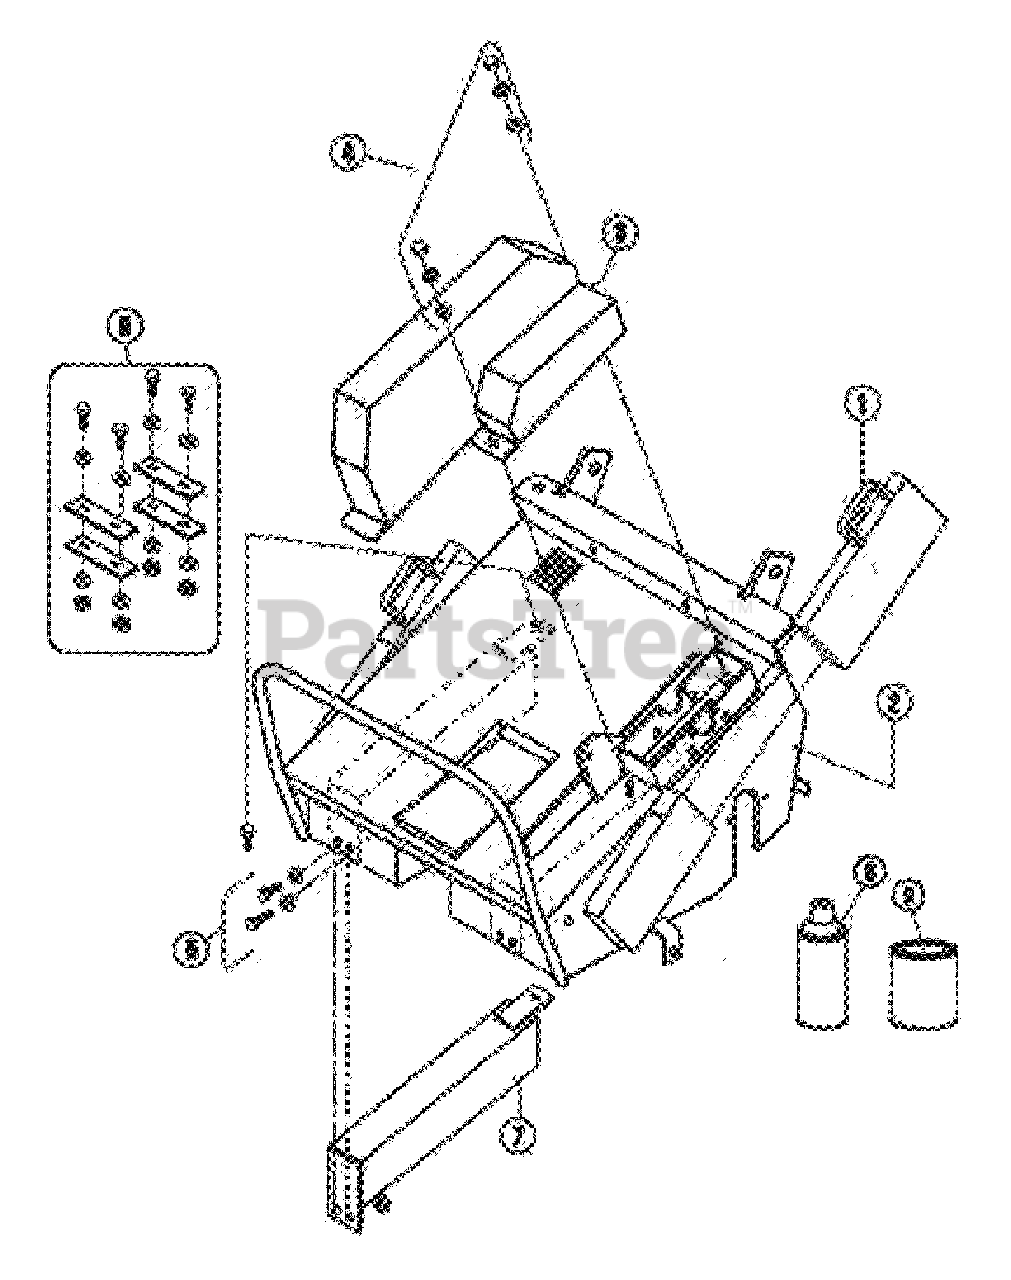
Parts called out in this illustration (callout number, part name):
1	Weight, 36 lbs., solid steel, removable
2	Housing with decals
3	Drive guard with decals
4	Drive guard fastener kit
5	Fastener kit, weight
6	Plate kit,
7	36 lb. weight, mounted
8	Paint, orange, 12.5 oz. can
9	Paint, orange, 1qt. can
10	Decal kit, AR25
